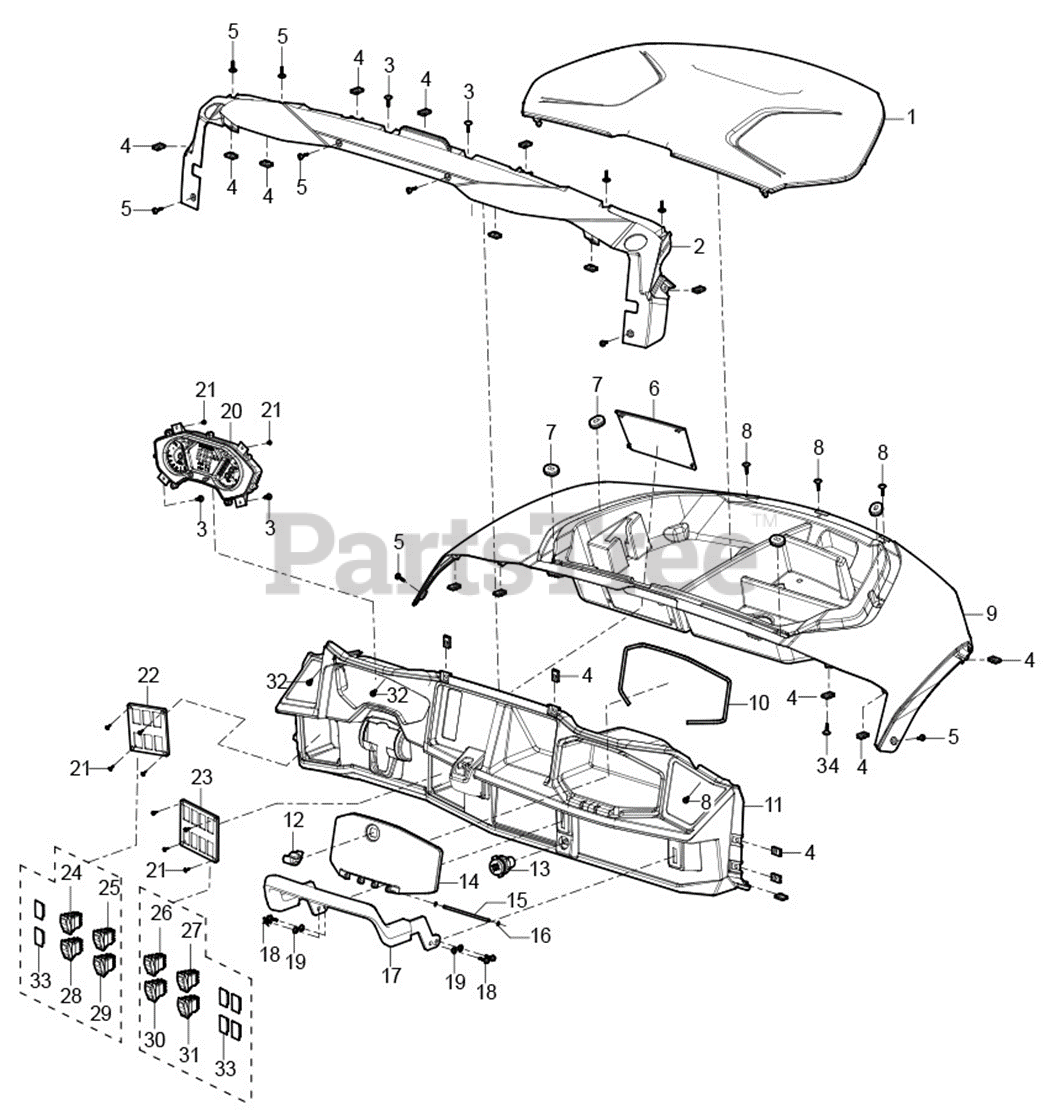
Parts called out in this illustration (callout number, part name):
2	DASH COVER SUPPORT
3	SCREW M6X16
4	CLAMP NUT M6X6
5	SOCKET HEX FLAT HEAD BOLT M6X16
6	DOOR ADJUSTING GEAR SELC CABLE RED
6	DOOR GEAR SELECT CABLE (YELLOW)
6	DOOR-GEAR SELECT CABLE BLUE
6	DOOR-GEAR SELECT CABLE BLACK
6	DOOR-GEAR SELECT CABLE CAMO
7	RUBBER WASHER
8	HEX HEAD CAP SCREW M6X16
9	HOOD (YELLOW)
9	HOOD (BLUE)
9	HOOD (BLACK)
9	HOOD (CAMO)
10	STORAGE BOX SEALING STRIP
11	DASH ASSEMBLY
12	STORAGE BOX COVER ASSEMBLY
14	STORAGE BOX COVER
15	STORAGE BOX COVER ROD
18	FLANGE BOLT M8X25
19	LOCK NUT M8
20	INSTRUMENT CLUSTER
21	SCREW - CROSS HEAD SELF TAPPING
22	SWITCH SUPPORT
23	SWITCH SUPPORT I
24	HEAD LIGHT SWITCH
25	SWITCH - OVERRIDE
26	SWITCH - 2W/4W
27	SWITCH - FRONT DIFFERENTIAL
28	SWITCH - EMERGENCY LIGHT
29	SWITCH - TURN
30	SWITCH - WINCH
31	SWITCH - REAR DIFFERENTIAL
32	SCREW M6-0.75:17.5
34	HEX HEAD FLANGE BOLT M6X12
